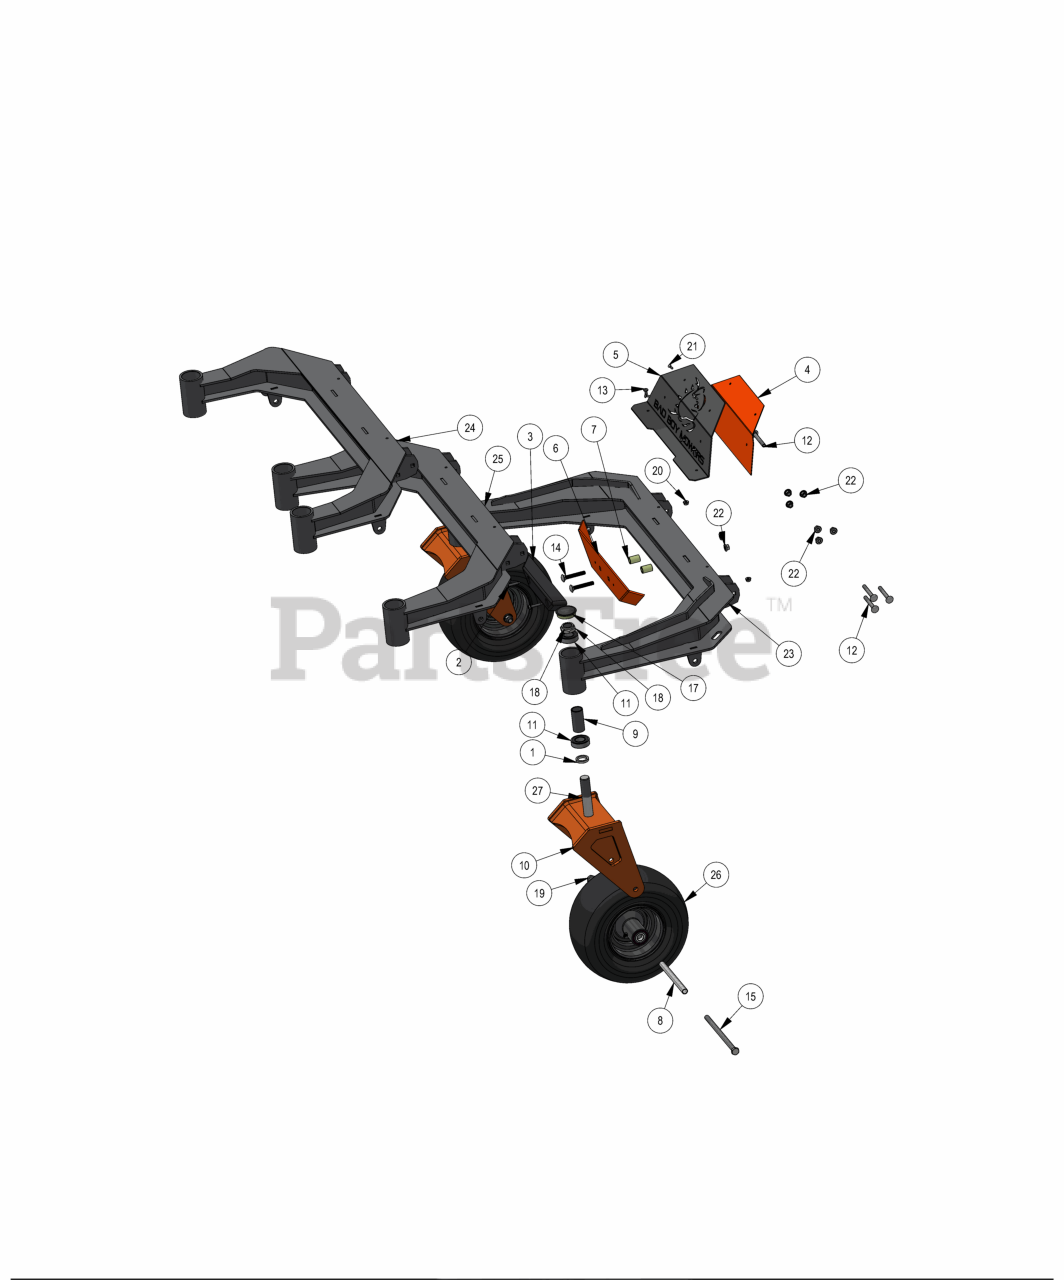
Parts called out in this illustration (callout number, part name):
1	1.02 ID X 1.38 OD X .250 THK SPACER ZINC
2	1/4-14 X 1-1/2 HEX WASHER UNSLOT TEK/3 ZINC
3	Bumper EZT
4	Exhaust Backer Plate 2019 Stand On
5	Exhaust Shield Plate 2019 Stand On
6	2019 Stand On Front Bumper Plate
8	Front Wheel Spanner
9	2016 Front Bearing Spacer
10	2019 Stand-on Front Fork Weldment
11	1641 BEARING W/2 CONTACT RUBBER SEALS
12	3/8-16 X 3 CARRIAGE BOLT ZINC GR5
13	1/4"-20 x 3/4 Black Oxide 18-8 Stainless Pan Head
14	3/8" x 2 1/2" Carriage Bolt
15	1/2-13 X 8-1/2 HEX CAP SCREW (GR.5) ZINC
16	1"-14 X 5-1/2 HEX CAP SCREW (GR.8) ZINC YELLOW
17	2017 Bearing Cover
18	1"-14 NYLON INSERT JAM LOCKNUT ZINC
19	1/2-13 NYLON INSERT FLANGE LOCKNUT ZINC
20	1/4-20 NYL INSERT FLANGE LOCKNUT ZINC
21	3/16" Diameter Black Rivet, for 0.1260"-0.25" Material Thick
22	3/8-16 NYLON INSERT FLANGE LOCKNUT (GR.F) ZINC
23	2023 Stand-On 61 Front End Weldment
24	2023 Stand-On 48 Front End Weldment
25	2023 Stand-On 54 Front End Weldment
26	13x6.50-6 Black No Flat Assembly
27	1"-14 X 5 HEX CAP SCREW (GR.8) ZINC YELLOW
